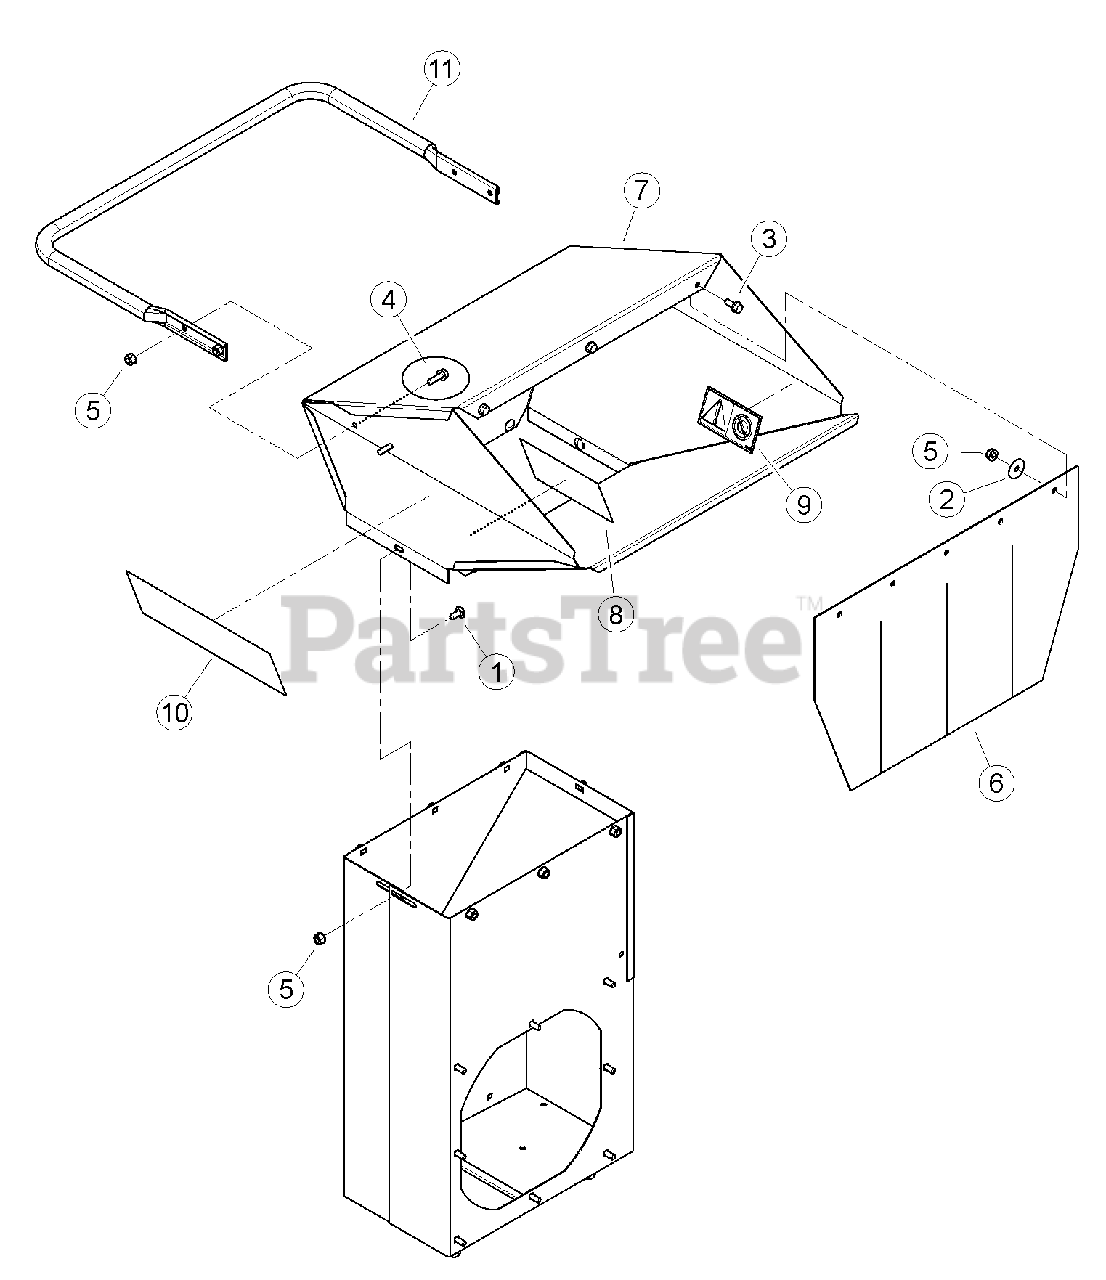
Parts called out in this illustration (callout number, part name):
1	BOLT, 5/16-18 X 3/4 SN GR5 CRG
2	WASHER, 5/16" FENDER ZP
3	BOLT, 5/16 X 3/4 FLANGE NC
4	BOLT, 5/16 X 1 FLANGE NC
5	NUT, 5/16-18 NYLOCK FLANGE
6	BELTING, RENTAL HOPPER
7	ASSEMBLY, NARROW RENTAL HOPPER W/ DECALS - SC3206 ONLY
8	DECAL, BLADE DANGER ISO
9	DECAL, SHREDDER SIZE ISO
10	DECAL, ECHO BEARCAT 12.00 X 4.00
11	HANDLE, RENTAL HOPPER
